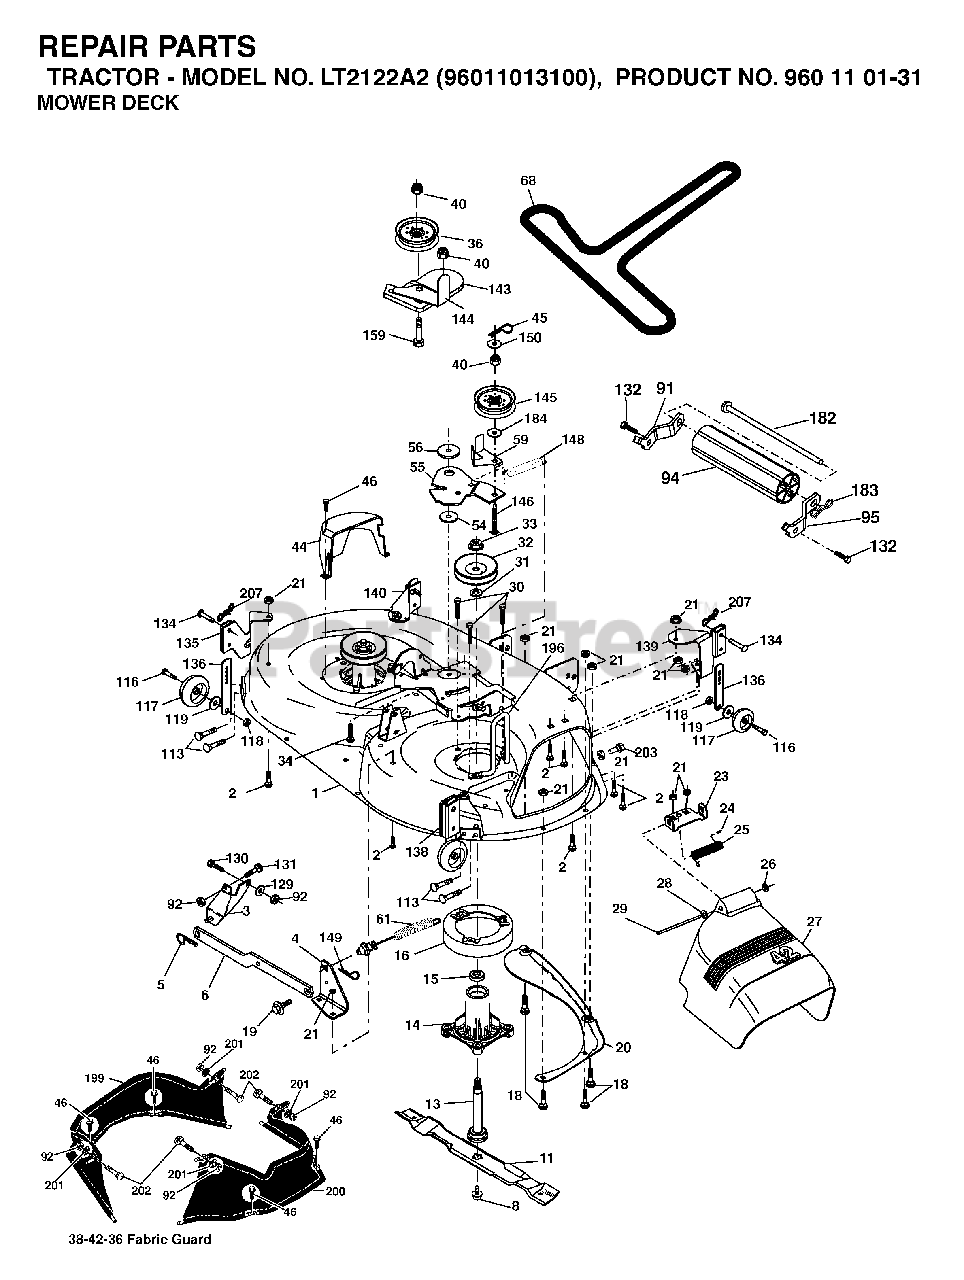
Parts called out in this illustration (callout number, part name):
1	MOWER DECK ASSY. 42"
2	BOLT
3	BRKT ASM SWAY BAR
4	BRACKET SWAY BAR 42" DECK
5	RETAINER-SPRNG RB
6	BAR SWAY DECK
8	BOLT.WASHER.ASM.7/16-2
11	42" HI-LIFT BLADE
13	SHAFT.ASM.MDRL.N/GREASE.38
14	HOUSING MANDREL
16	STRIPPER, MWR ROUND
18	BOLT
19	BOLT SHD 5/16-18
20	BAFFLE.VORTEX
21	LOCKNUT
23	BRKT, DEFL. MOWER
24	CAP-SLEEVE LT
25	SPRING TORSION
26	NUT PUSH M
28	WASHER
29	ROD.HINGE
30	SCREW, WASHER HEAD
31	WASHER.SPACER.MANDREL
32	PULLEY/MANDREL
33	NUT.FLANGE.LOCK.TOP
34	BOLT.3/8-16X1.50
36	FLAT IDLER PULLEY
40	NUT LOCK FLG 3/8-16 UNC
44	GUARD MANDREL LH BLACK
45	RETAINER M
46	SCREW.1/4-20X5/8
55	ARM IDLER 42" MOWER LT/YT
56	SPACER.RETAINER.MOWER
59	GUARD, BELT
61	SPRING EXT ELEC CLUTCH
91	BRACKET ASM NOSEROLLER LH
92	NUT
94	NOSE ROLLER
95	BRACKET ASM NOSEROLLER RH
113	BOLT.5/16HEX.WHS.HD
116	BOLT.SHOULDER.3/8-16X3-5/8
117	WHEEL. GUAGE RALLY
118	LOCKNUT
119	WASHER
129	WASHER
131	BOLT D
132	SCREW, 3/8-16X3/4
134	RIVET.PIN.HEAD.YELLOW
135	BRACKET ASSY
136	BAR.ADJUST.WHEEL.ANTI.SCALP.BL
138	GAUGE WHEEL BRACKET ASSY
140	BRACKET ASSY
143	BRACKET, ARM IDLER
144	KEEPER.BELT.42".CLUTCH.CABLE
145	PULLEY
146	BOLT, CARRIAGE IDLER BLACK
148	IDLER RETURN SPRING
149	SPRING.RETAINER.YELLOW.ZINC
150	WASHER LT
159	BOLT
182	ROD ROLLER NOSE STANDARD
183	PIN.COTTER.7/16.BOW TI
184	WASHER
201	PUSH.NUT.ROUND.3/8.DIAM
205	PIN.COTTER.5/16.BOW TI
